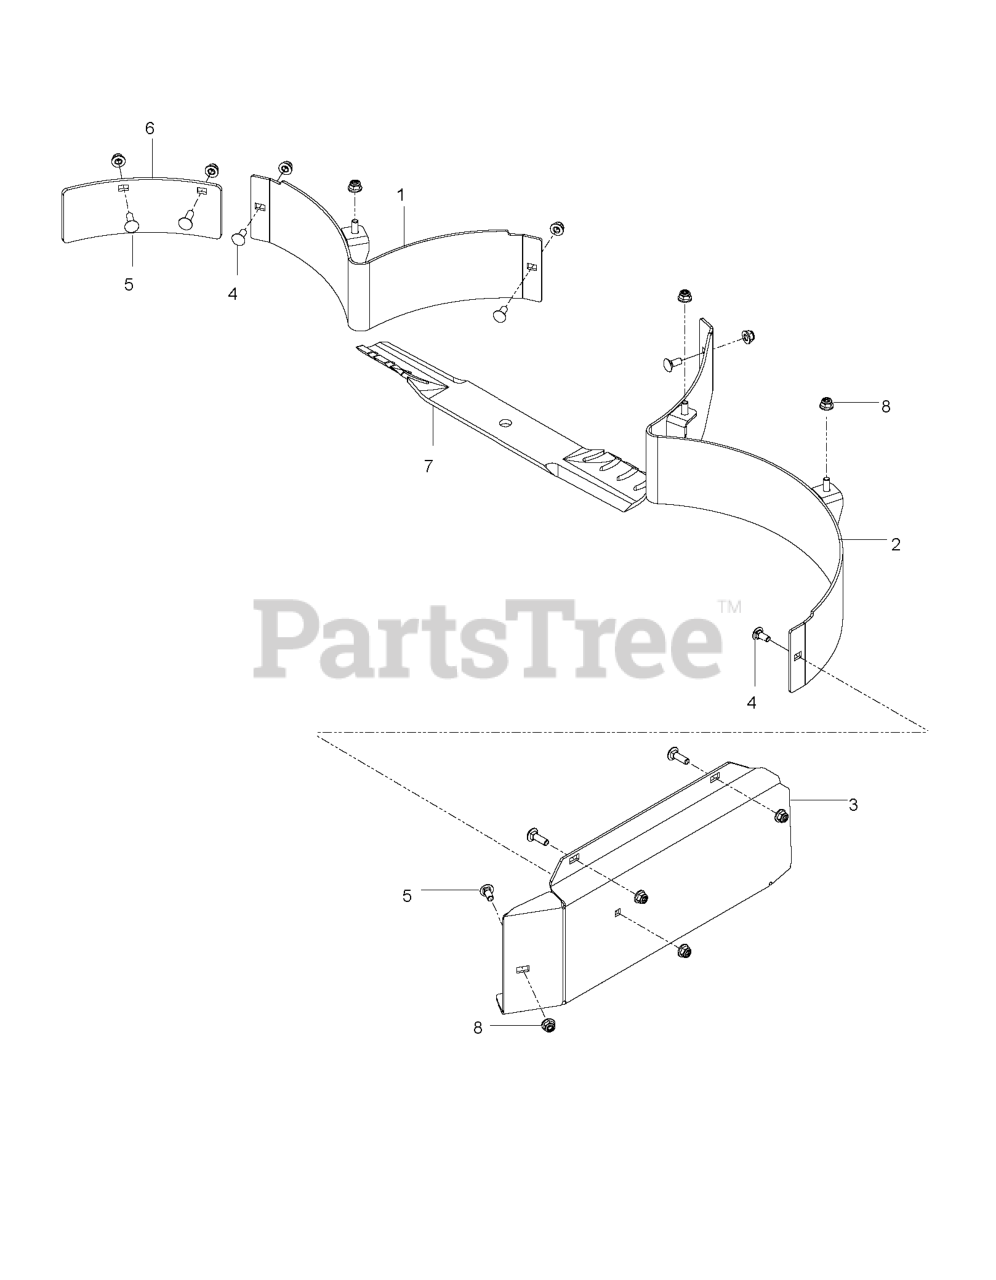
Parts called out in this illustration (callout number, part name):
1	MULCH BAFFLE 54" LH PAINTED
2	MULCH BAFFLE RH 54" BLACK
3	CAP, MULCH 54" BLACK
4	BOLT 5/16C X 3/4" CARRIAGE
5	RHSNB 5/16C X 1
6	BAFFLE, 60" LH CORNER BLK
7	BLADE, 19" GATOR, 1.25" LIFT
8	5/16-18 NYLOC FLANGE NUT
